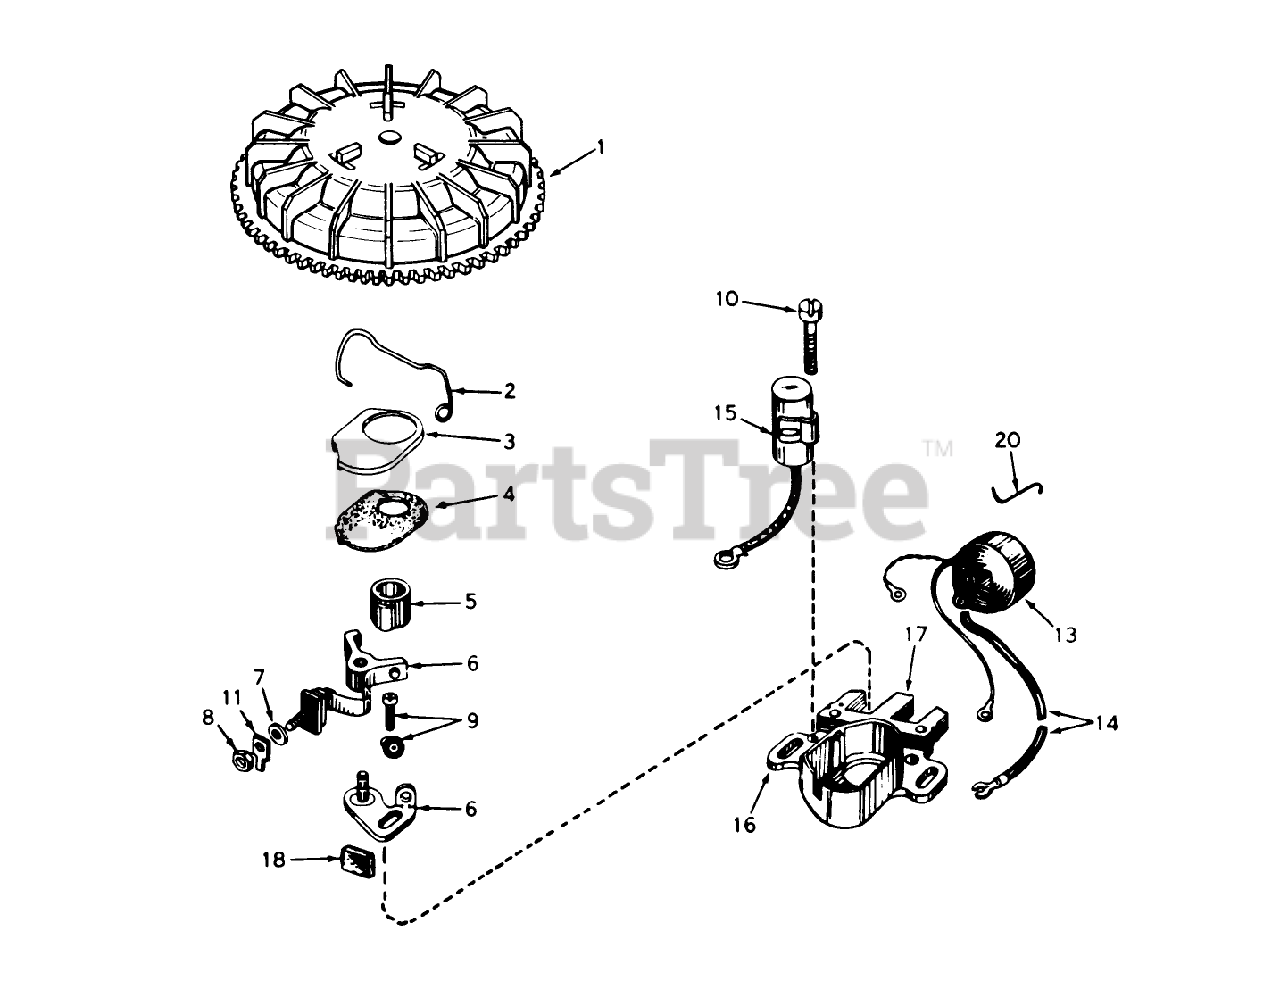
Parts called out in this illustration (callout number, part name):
1	Flywheel (Incl. Ref #3 4)
1	Flywheel (Incl. Nos. 3 4)
2	Spring Breaker Box
3	Cover-Dust
4	Gasket, Dust Cover
5	Cam, Breaker
6	Breaker Assy.
7	Washer
8	DECAL
9	Breaker Screw
10	Condenser Screw
11	Terminal, Ground
13	Coil Assy. (Incl. No. 12)
14	Wire, Lead
15	Condenser
16	Core Plate
17	Stator Assy. (Incl. Ref. #2 thru 11, 13, 14, 16, 17 19)
18	Felt,Cam Wiper
20	Clip, Coil
